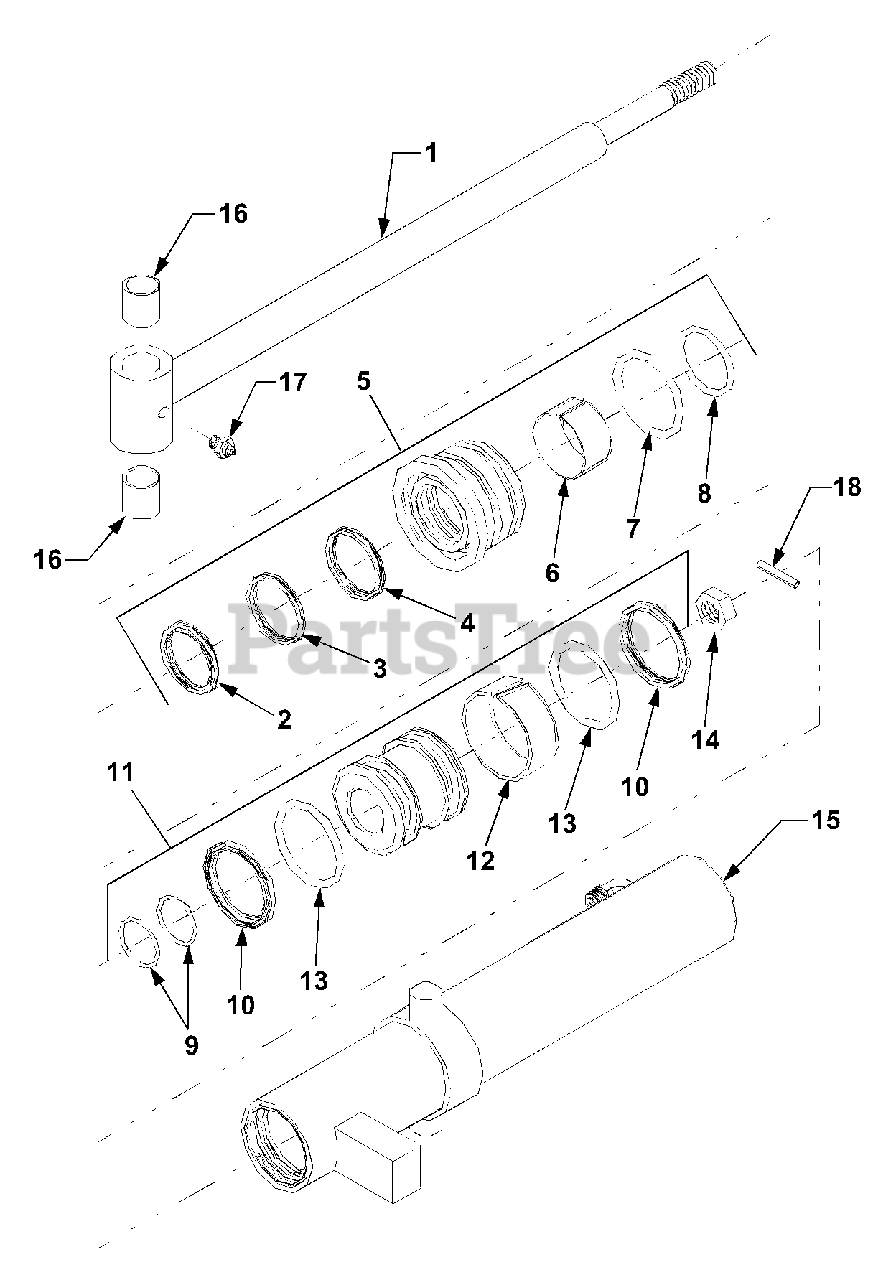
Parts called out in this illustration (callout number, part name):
3	Retainer (Rubber)
4	Retainer (Urethane)
5	Head and Seal Kit
11	Piston and Seal Kit
15	Tube Assembly
17	Grease Nipple
